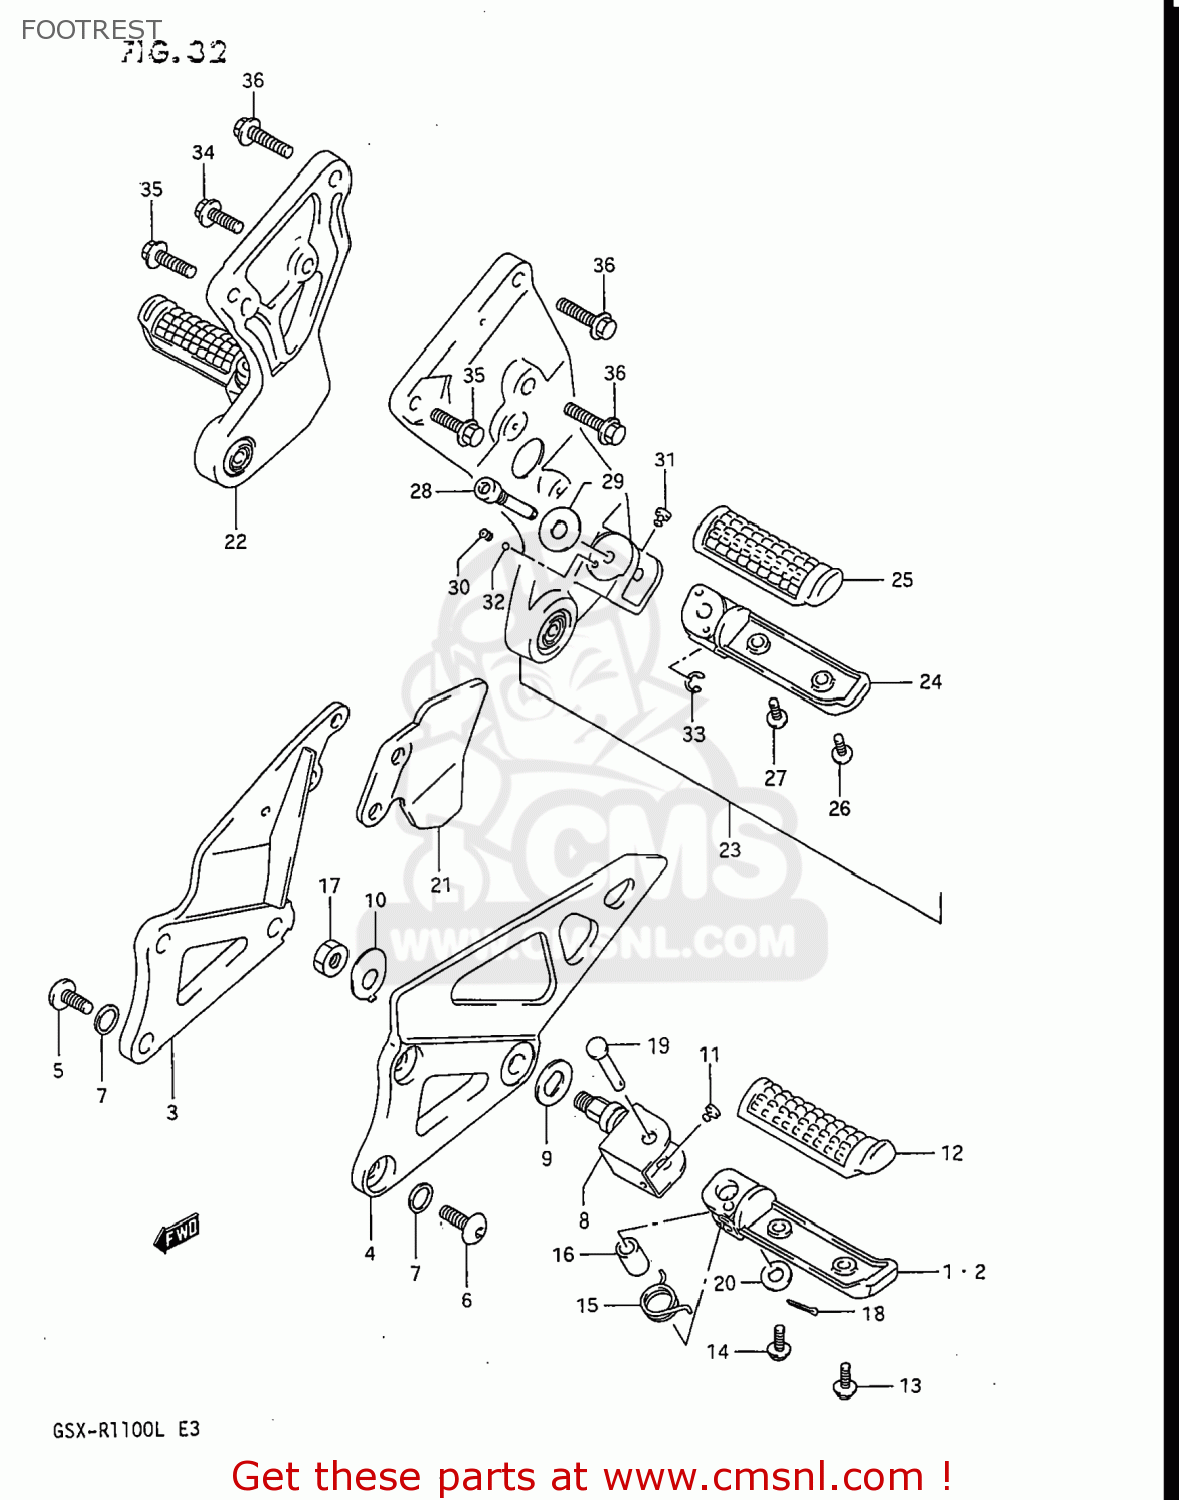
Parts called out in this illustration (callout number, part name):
1	BAR,FOOTREST,R
2	BAR,FOOTREST,L
3	BAR,FRONT FOOTREST
4	BRACKET,FOOTREST,LEFT
5	BOLT,FRONT FOOTREST
6	BOLT,FOOTREST BRACKET
7	WASHER
8	HOLDER,FOOTREST,RIGHT
9	PLATE,FOOTREST INNER
10	WASHER,FR FOOTREST
11	CUSHION,FOOTREST
12	RUBBER,FOOTREST
13	SCREW
14	SCREW
15	SPRING
16	SPACER(8.1X12X22)
17	NUT 12MM
18	PIN 20X15
19	PIN
20	WASHER
21	GUARD,FRONT FOOTREST,RIGHT
22	FOOTREST ASSY,PILLION,R
23	FOOTREST ASSY,PILLION,L
24	BAR,PILLION FOOTREST,R
25	RUBBER,FOOTREST
26	SCREW
27	SCREW
28	BOLT,PILLION FOOTREST
29	WASHER
30	SPRING
31	CUSHION,FOOTREST
32	BALL
33	E RING 6MM
34	BOLT
35	BOLT
36	BOLT
